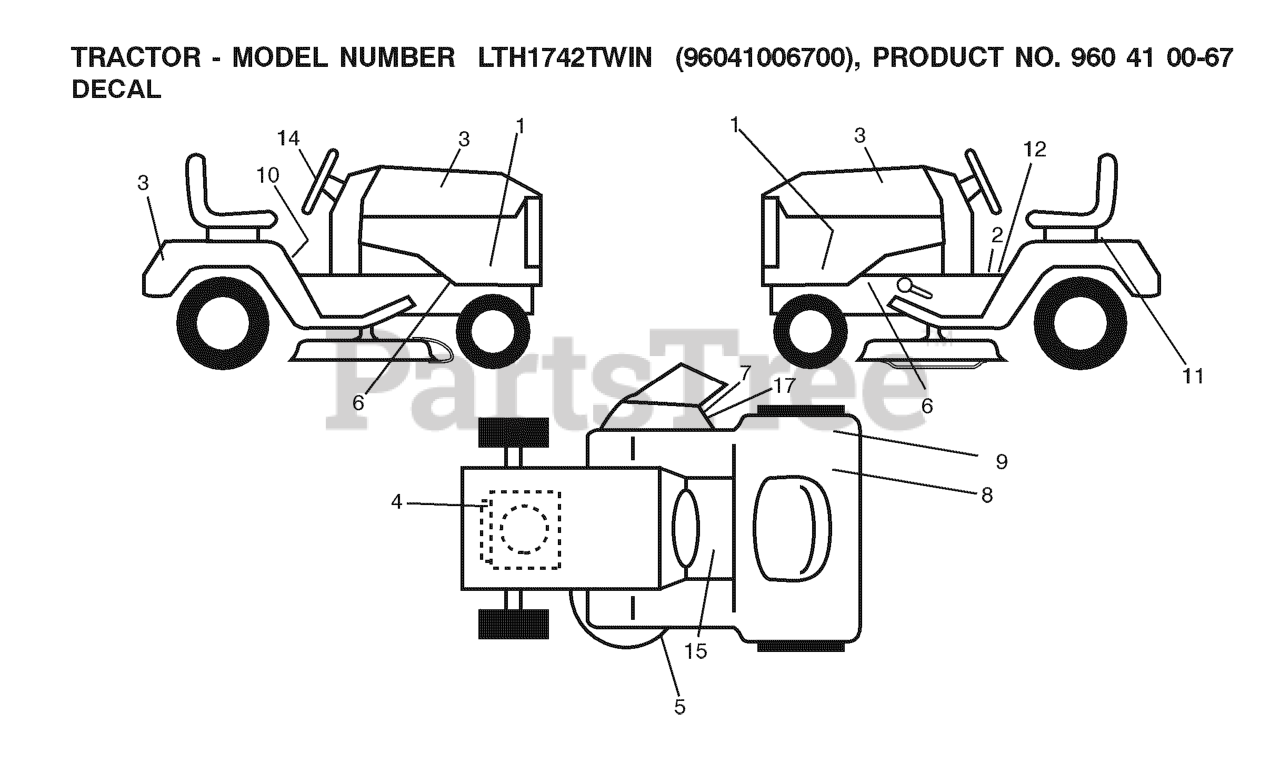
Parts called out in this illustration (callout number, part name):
2	DECAL PARK BRAKE
3	DECAL.HOOD.NAMELOGO.HUSQ
4	DECAL
5	DECAL V BELT SCHEMATIC
7	DECAL.INTERNATIONL.CUTFINGER
8	DECAL 80 DBA
9	DECAL
10	LABEL
11	DECAL BTRY SYMBOLS
12	DECAL
14	DECAL.WHEEL.STRG.LGN.H
15	DECAL
17	DECAL, DEFLECT WARNING
